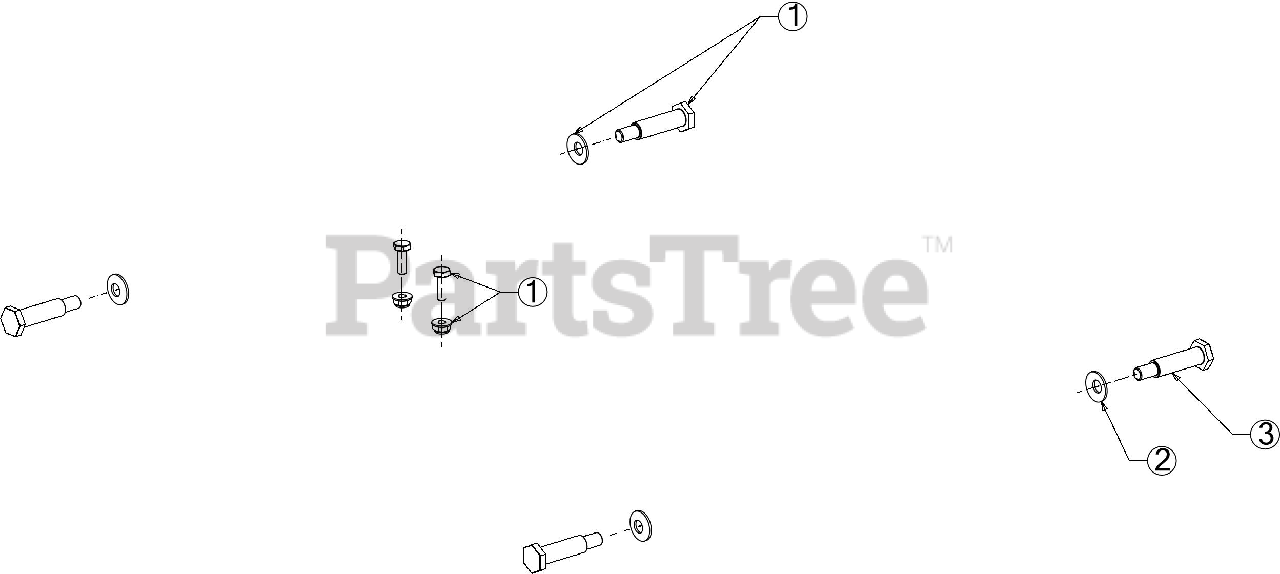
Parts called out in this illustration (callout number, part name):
1	HARDWARE PACK
1	SCREW 1/4-20X.75 GR5
1	FLANGE LOCK NUT
1	BELL WASHER .400 ID x .88 x .060
1	SHOULDER SCREW
2	BELL WASHER .400 ID x .88 x .060
3	SHOULDER SCREW
